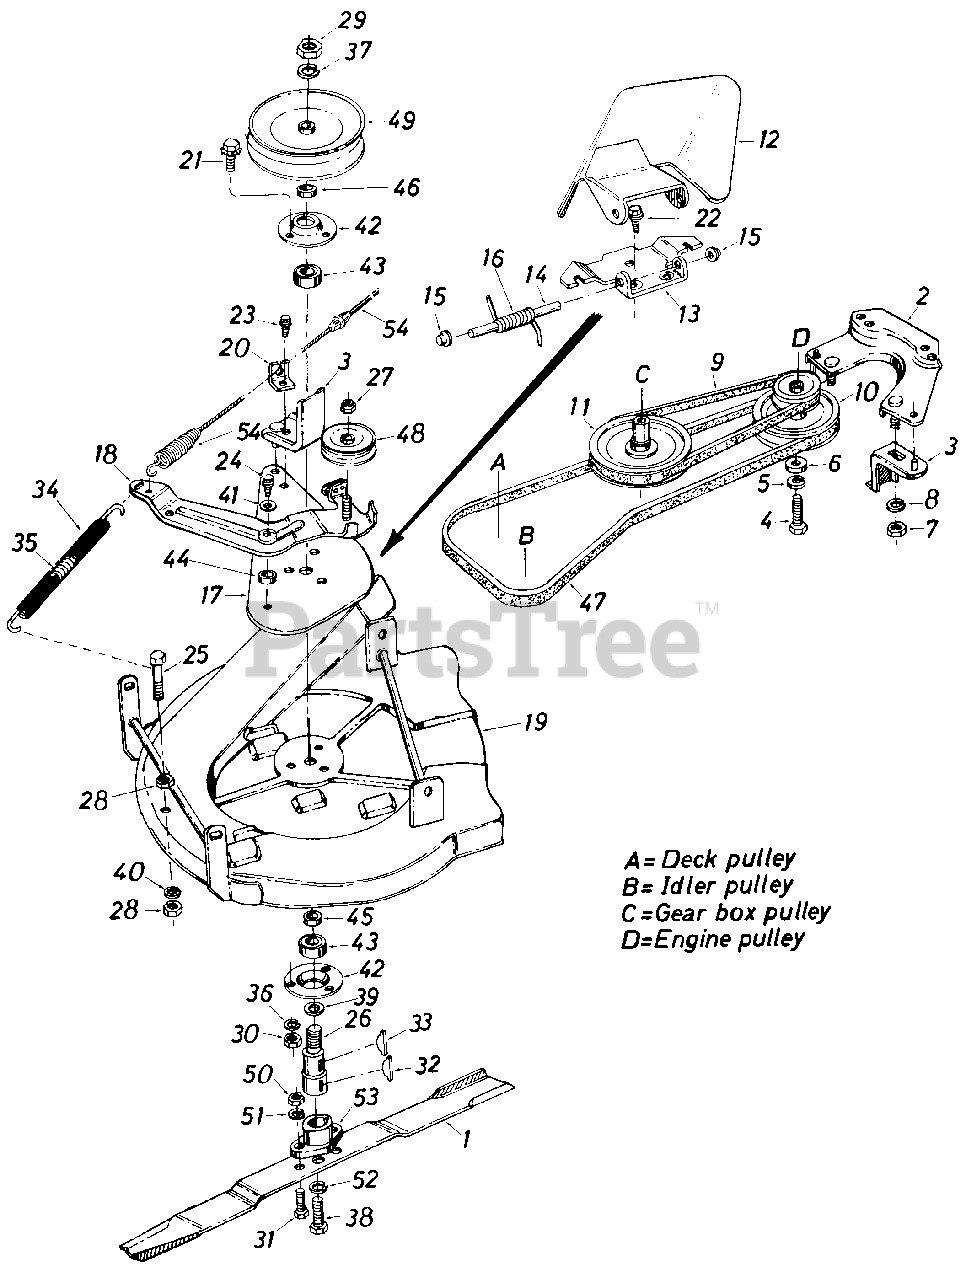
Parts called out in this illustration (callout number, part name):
1	26" Blade
2	Belt Guard Cup Ass'y.
3	Belt Keeper Ass'y.
4	Hex Bolt 3/8-24 x 1.00" Lg.
5	L-Wash. 3/8" I.D.
6	Fl-Wash. .406" I.D. x 1.25" O.D.
7	Hex Nut 5/16-18 Thd.
8	L-Wash. 5/16" I.D.
9	3V-Belt 28" Lg.
10	Double Pulley
11	3/8" V-Pu I ley .502" I.D. x 6.5" O.D.
12	Chute Cover Ass'y. Comp.
13	Adapter Plate
14	Hinge Pin
15	Cap Speed Nut 1/4" Rod
16	Torsion Spring
17	Deck Belt Guard Plate
18	Deck Idler Brk't. Ass'y.
19	26" Deck Ass'y.
20	Cable Support Brk't.
21	Hex Sems Bolt 5/16-18 x 1.00" Lg.
22	Hex Wash. S-Tap Scr. 1/4-20 x .50" Lg.
23	Hex Wash. Hd. B-Tap Scr. 5/16-18 x .50" Lg.
24	Hex L-Bolt 5/16-18 x 1.00" Lg.
25	Hex Bolt 1/4-28 x 1.50" Lg.
26	Blade Spindle
27	Hex Ins. L-Nut 3/8-24 Thd.
28	Hex Cent. L-Nut 1/4-28 Thd.
29	Hex Jam Nut 5/8-11 Thd.
30	Hex Nut 5/16-18 Thd.
31	Hex Bolt 5/16-24 x 1.00" Lg. (Grade 8)
32	#6 Hi-Pro Key 5/32 x 5/8" Dia.
33	#61 Hi-Pro Key 3116" x 5/8" Dia.
34	Plastic Tube .52" I.D. x 7.0" Lg.
35	Ext. Spring .50" O.D. x 5.2" Lg.
36	L-Wash. 5/16" I.D.
37	L-Wash. 5/8" I.D.
38	Hex Bolt 3/8-24 x 1.50" Lg. Grade 5
39	Bearing Shield
40	L-Wash. 1/4" I.D.
41	Fl-Wash. .330" I.D. x 1.25" O.D. x .120
42	Bearing Housing
43	Ball Brg. .787" I.D. x 1.85" O.D.
44	Spacer.315" I.D. x .75" O.D. x .37" Lg.
45	Spacer.836" I.D. x 1.01" O.D. x .320" Lg.
46	Spacer .630" I.D. x 1.135" O.D. x .195" Lg.
47	"V"-Belt-A Sec. x 59.0" Lg.
48	"V"-ldler 3.06" O.D.
49	5/8" V-Pulley .625" I.D. x 7.0" O.D.
50	Hex Nut 5/16-24 Thd.
51	L-Wash. 5/16" I.D.
52	L-Wash. 3/8 I.D. Heavy Duty
53	Blade Adapter Kit
54	Clutch Cable 56.0"
